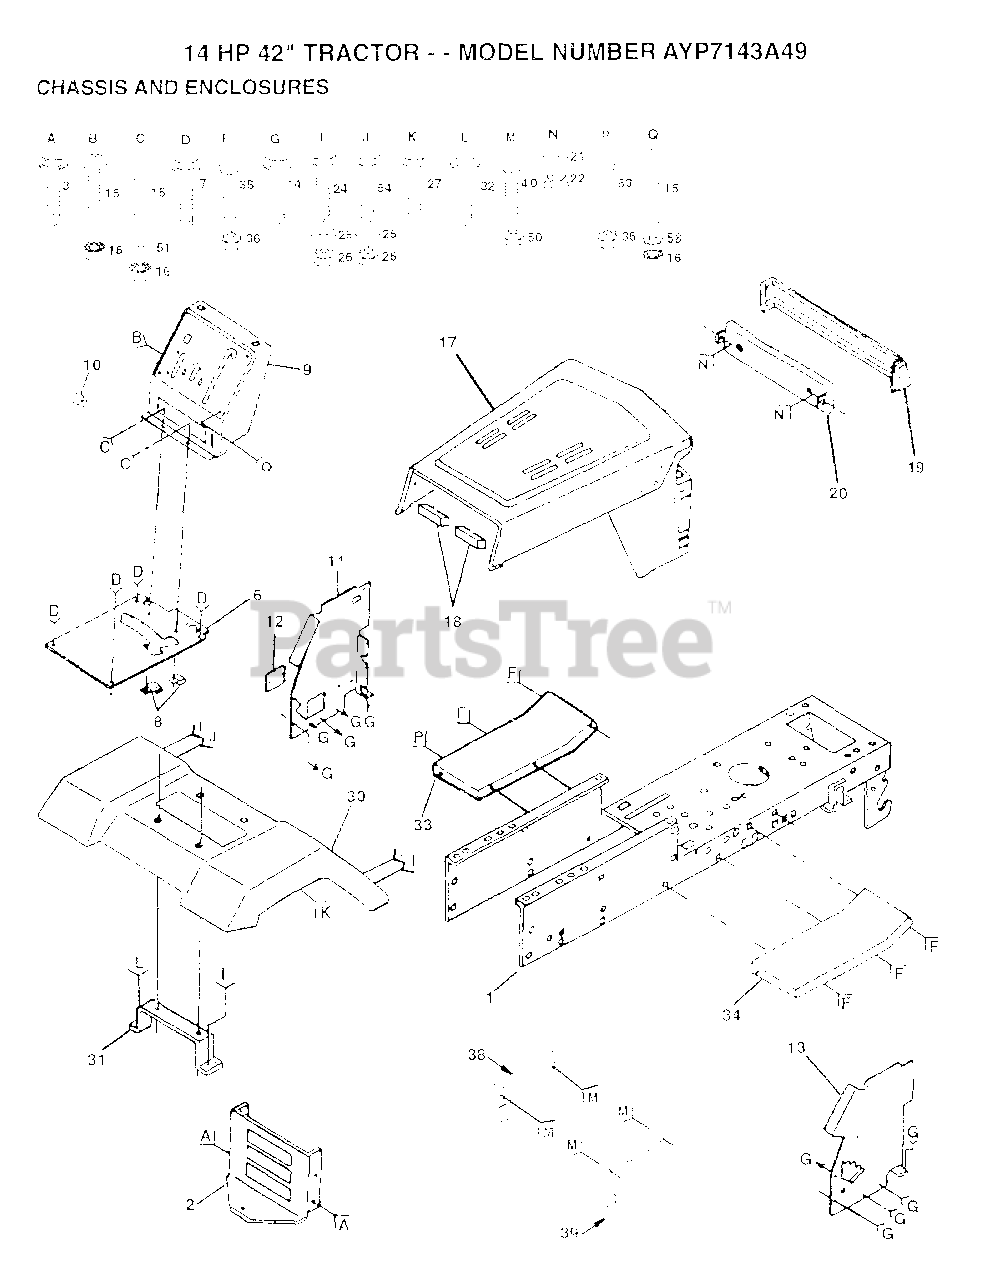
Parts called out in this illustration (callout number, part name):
3	SCREW
7	SCREW LT
8	CLIP T
9	DASH.SLKSCR.1.PC
10	PLUG BUTTON T
11	PANEL DASH LH
12	COVER ACCESS
14	SCREW LT
15	SCREW
17	HOOD/GRILL ASM
21	WASHER PM
22	PAL NUT LT
25	WASHER
27	SCREW LT
30	FENDER
31	BRKT FENDER
32	SCREW
33	FOOTREST LH
34	FOOTREST RH
35	BOLT
38	PIVOT BRKT LH
39	PIVOT BRKT RH
50	NUT
51	WASHER
58	LOCKWASHER
